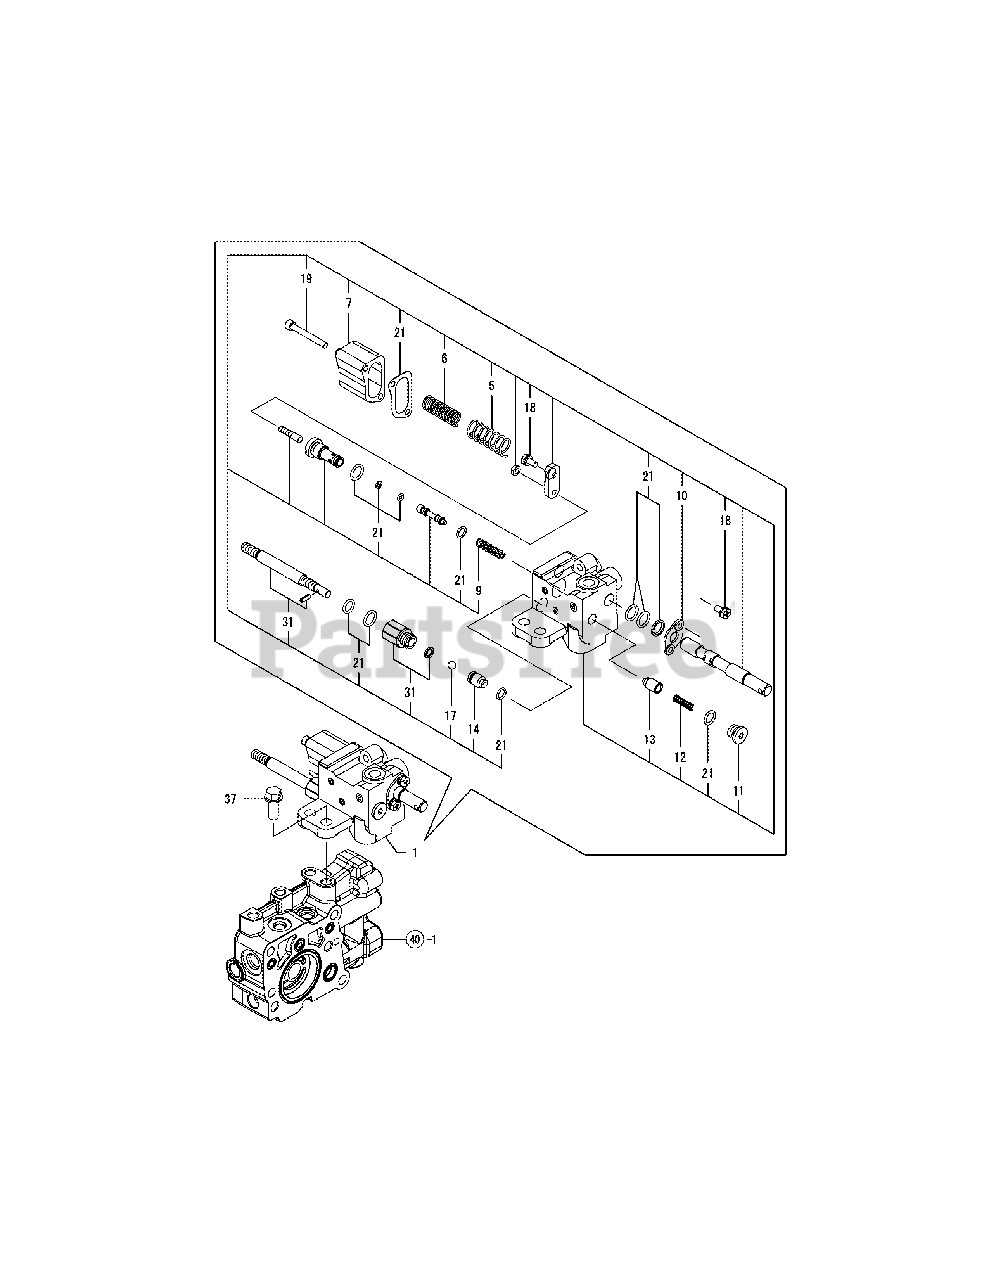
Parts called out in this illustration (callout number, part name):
1	Valve Assy, Lift
5	Spling, Lift Valve
6	Spling, Lift Valve
7	Cover, Lift Valve
9	Spring, Mecha, Valve
10	Plate, Lift Valve
11	Plug, Lift Valve
12	Spring, Lift Valve
13	Poppet, Check, Valve
14	Plunger, Lift Valve
21	Seal Kit, Lift Valve
31	Stop Bolt Kit, Valve
